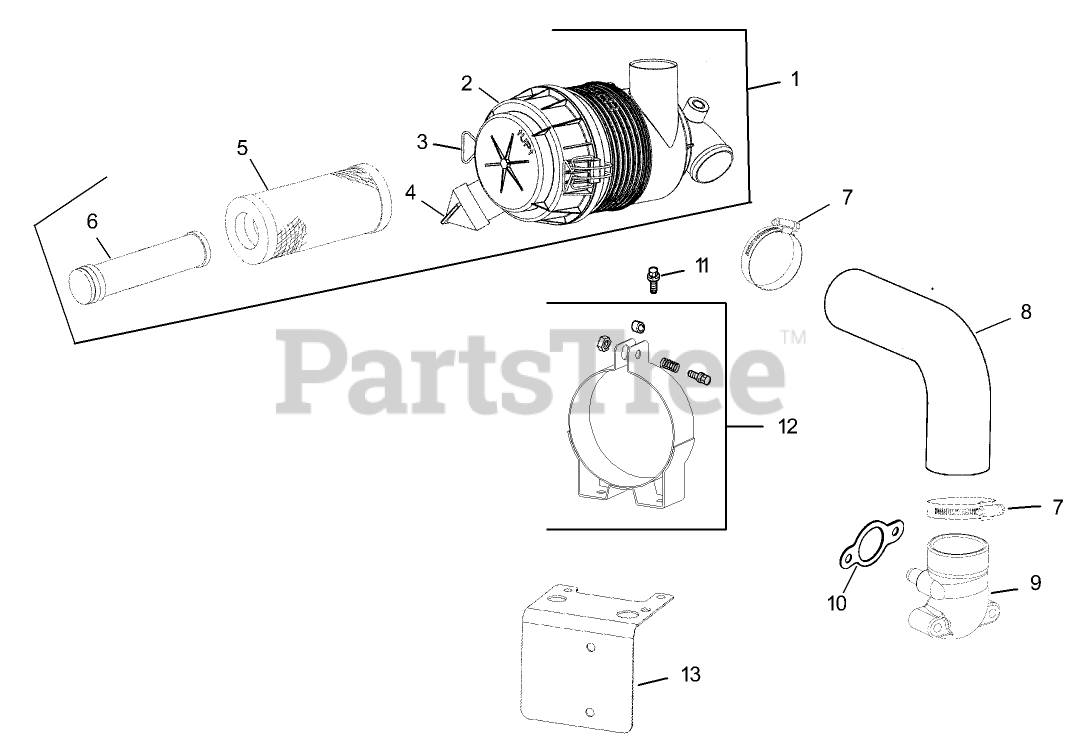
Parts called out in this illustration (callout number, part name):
1	Cleaner assembly, air (Includes 2-6)
2	Cover assembly, plastic air cleaner
3	Clip
4	Valve-Ejector, Dust
5	Element, air-primary
6	Element, air-safety
7	Clamp, hose
8	Hose, air cleaner
9	Elbow assembly
10	Gasket-Base, Air Cleaner
11	Screw, hex. flange
12	Bracket assembly, air cleaner support
13	Bracket, air cleaner
